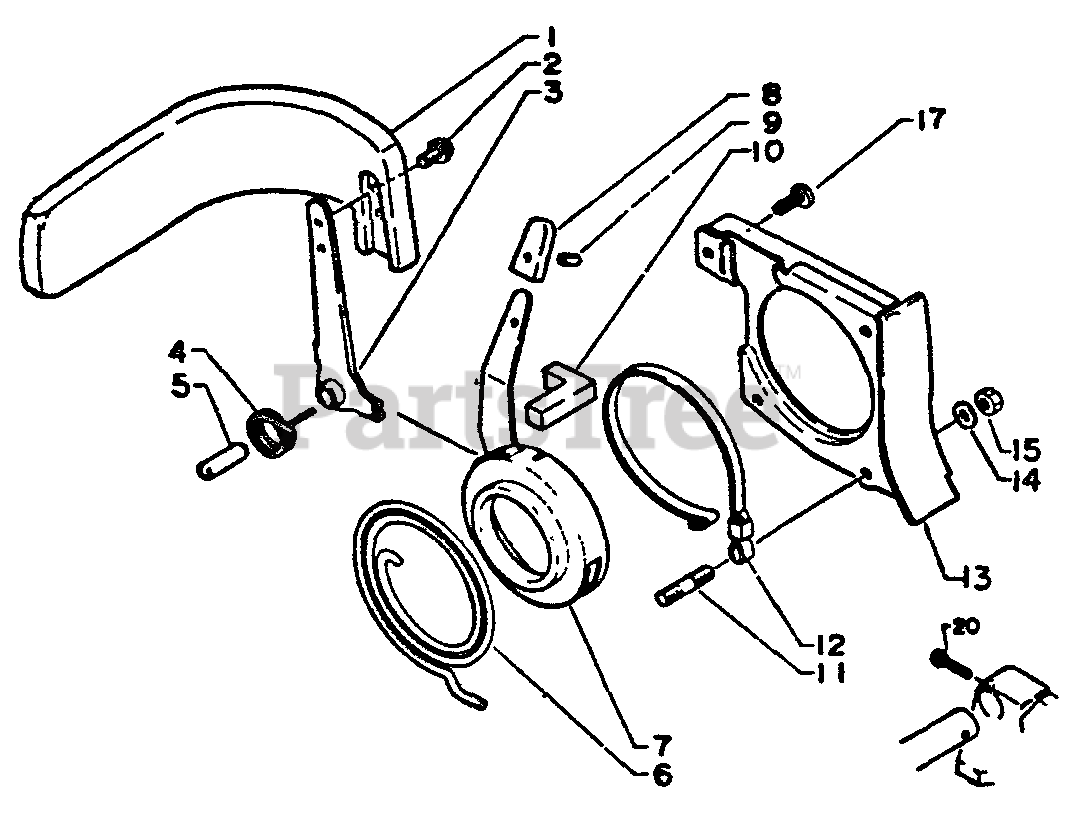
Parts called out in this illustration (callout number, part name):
1	HANDLE, BRAKE
2	SCREW - 4X12
3	LEVER, BRAKE
4	SPRING, RETURN
6	SPRING, BRAKE
7	CASE, BRAKE BAND
8	RESET, BRAKE
9	PIN - SPRING -- 3X8
10	SEAL, DUST
11	STUD
12	BAND, BRAKE
17	SCREW - 4X10
20	SCREW - 4X20
